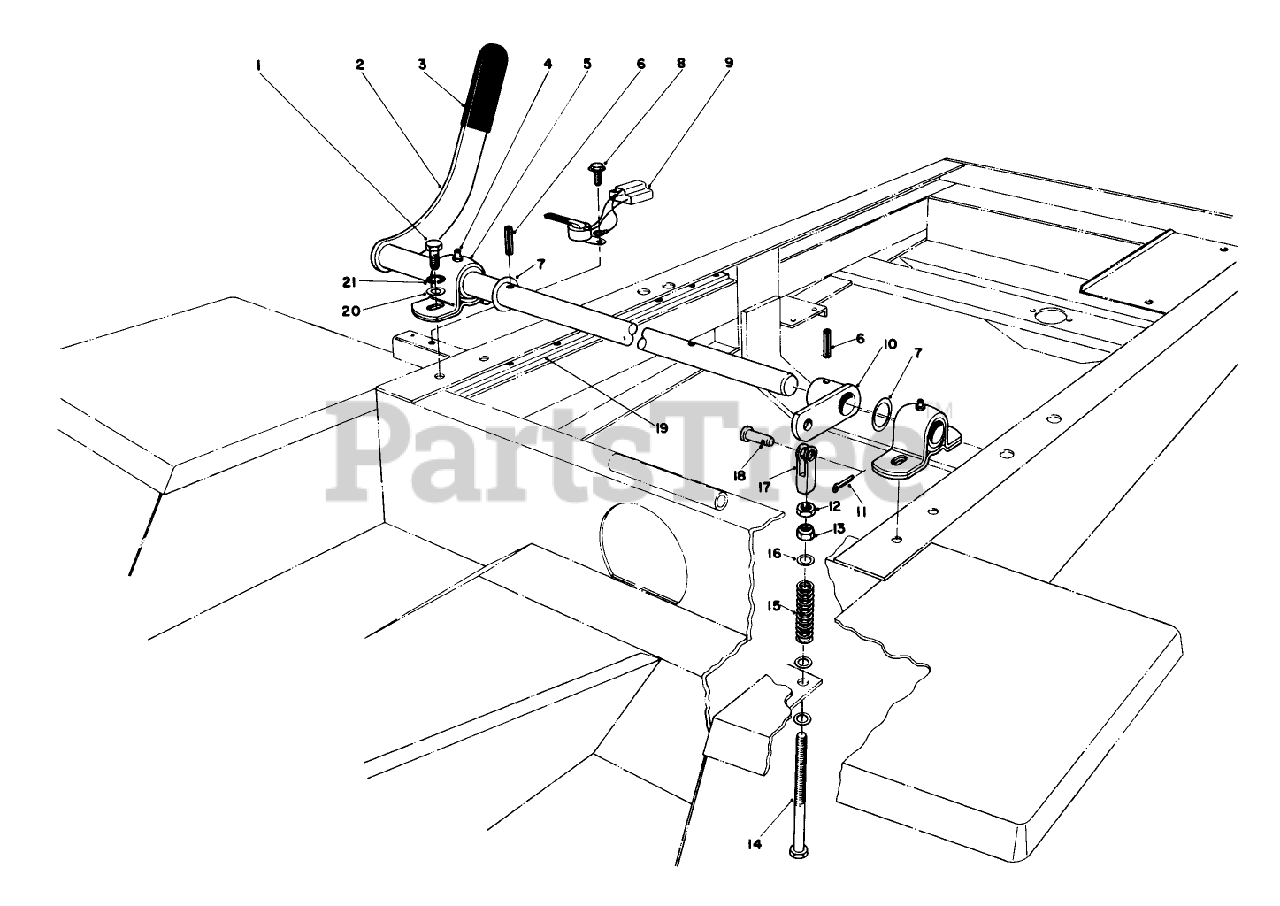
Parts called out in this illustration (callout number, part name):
1	SCREW-HH
2	P.T.0. Lever
3	GRIP-HANDLE
4	FITTING-GREASE
5	BEARING
6	PIN-SPRING
7	THRUST WASHER
8	SCREW-THD FRM,HWH
9	PTO SWITCH
10	ENGAGE ARM WA
11	PIN-COTTER
12	SCREW-CARR
13	NUT-HEX
14	SCREW-ADJUSTING
15	SPRING-COMPRESSION
16	WASHER
17	Yoke
18	PIN-CLEVIS
19	Bar Frame Rail
20	WASHER-FLAT
21	WASHER-LOCK
